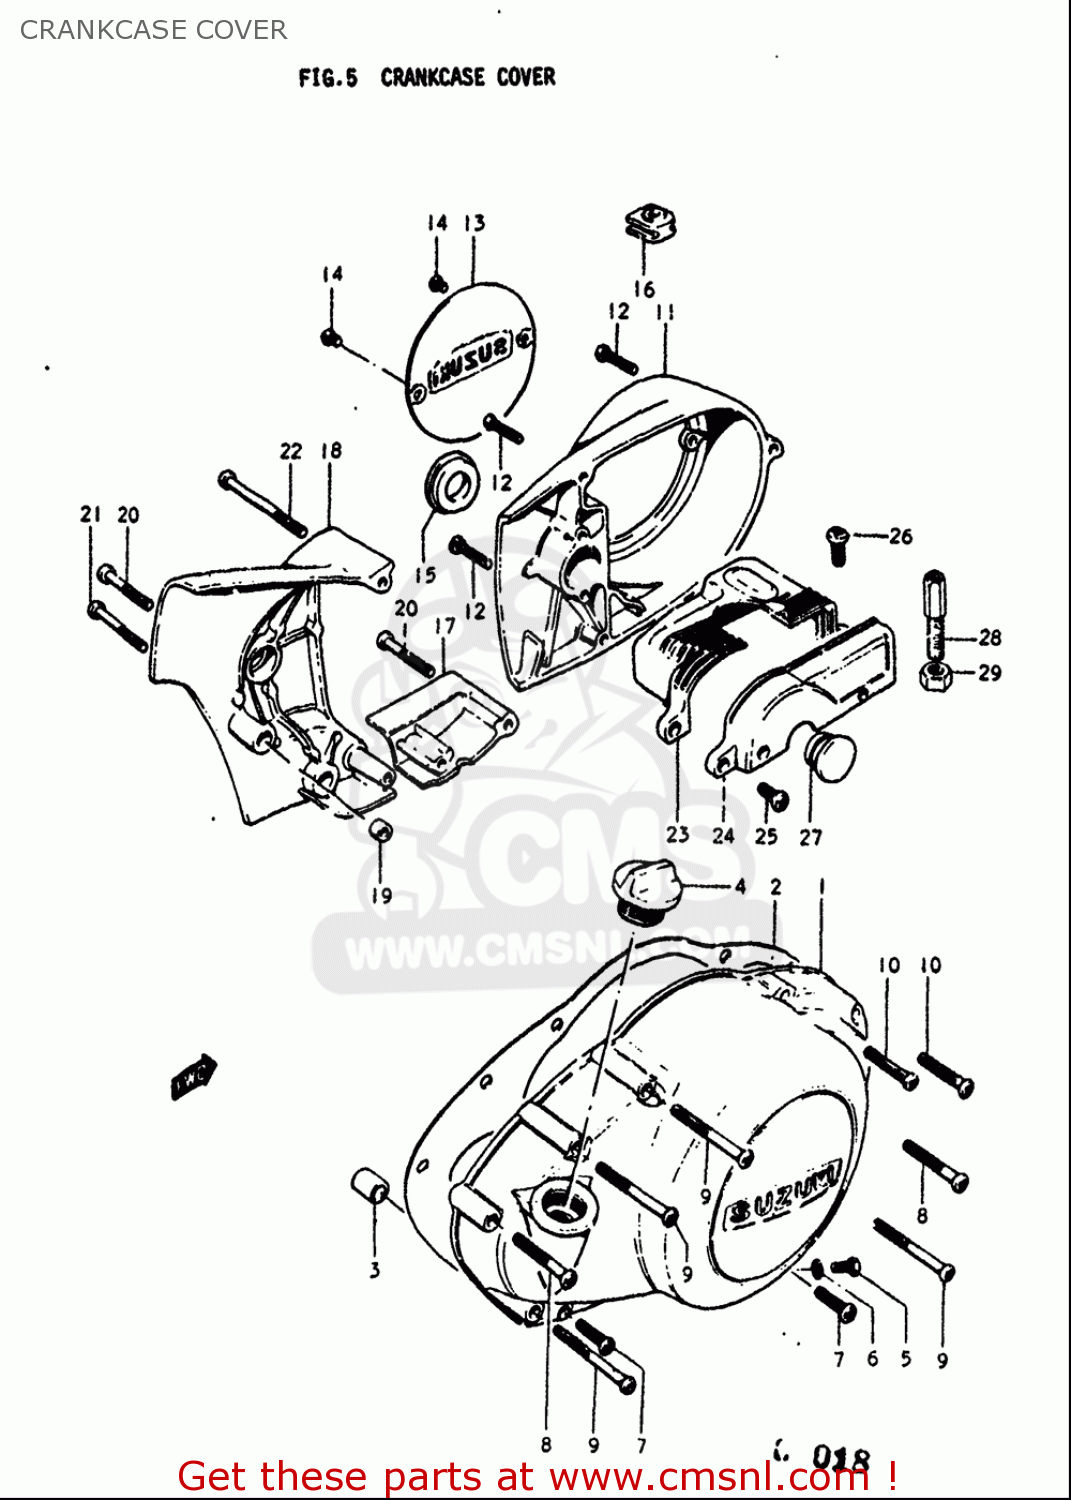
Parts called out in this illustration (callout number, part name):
2	GASKET,CLUTCH COVER (NAS)
3	PIN
4	PLUG
5	SCREW(6X10)
6	GASKET(6.2X11X1) (NAS)
7	SCREW
8	SCREW
9	SCREW
10	SCREW
12	SCREW
14	SCREW
15	CAP(OD:36)
19	PIN
20	SCREW
21	SCREW
22	SCREW
25	SCREW
26	SCREW
27	CAP(OD:26)
28	BOLT
29	NUT
